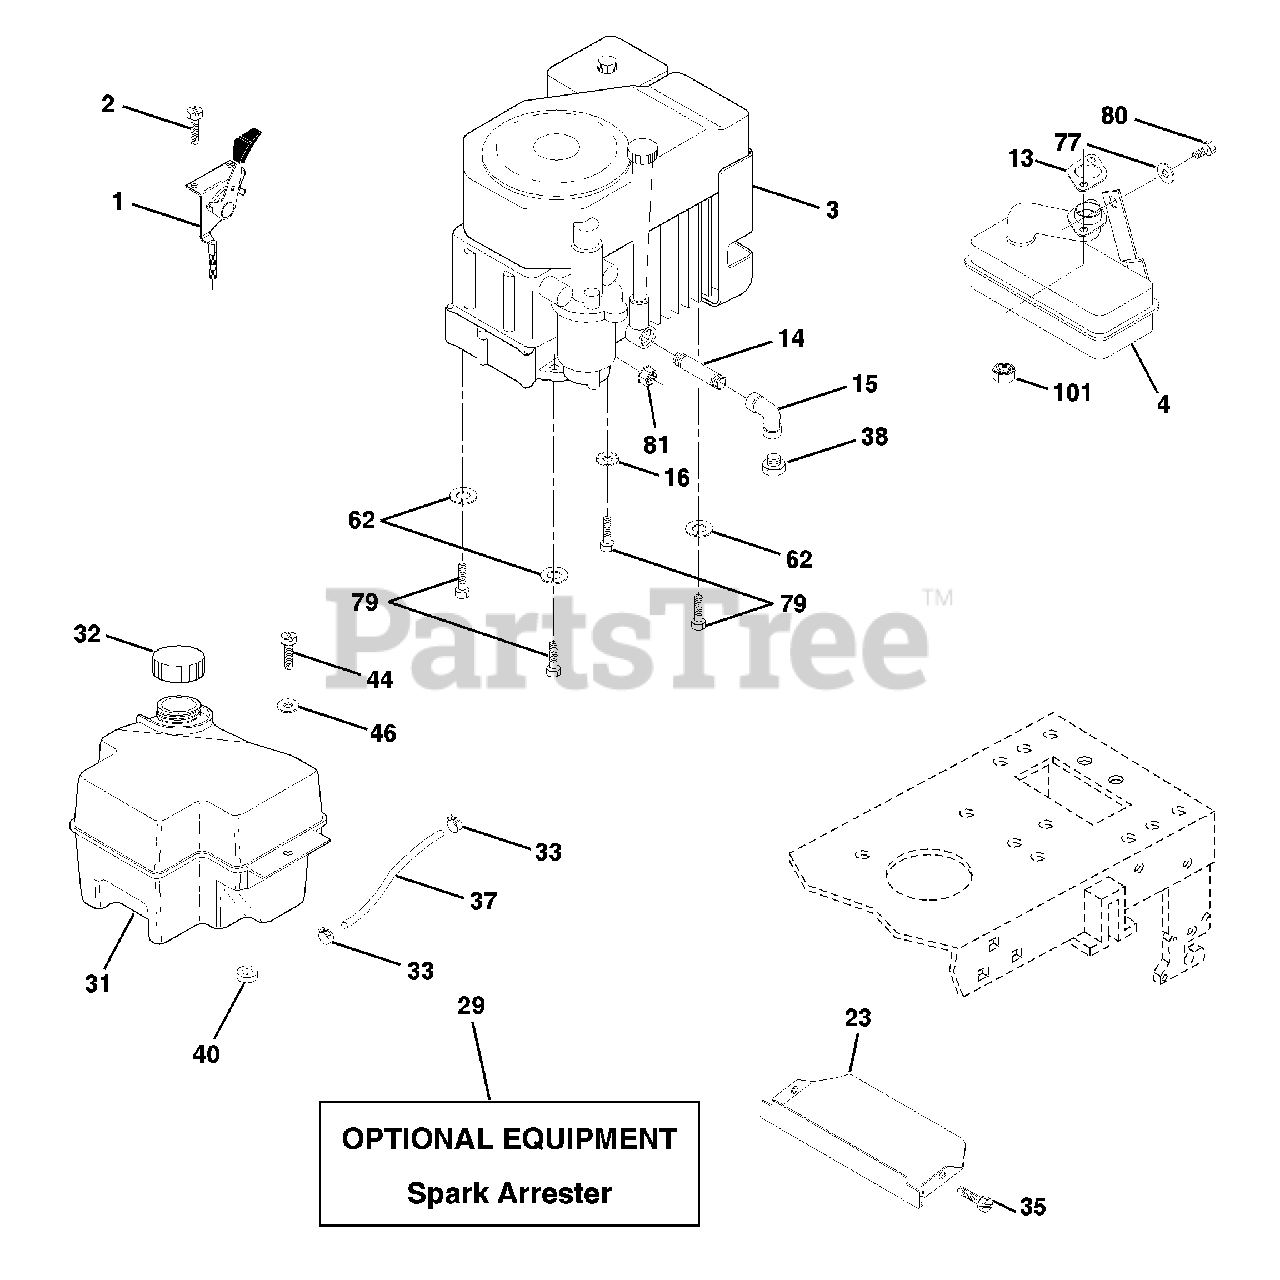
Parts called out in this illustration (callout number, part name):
1	Control THT/CH 27 LH FLAG DOM
2	Screw Hex Thd Cut 1/4-20 x 5/8 T
4	Muffler LT Kohler
13	Gasket Kohler CV13-CV16.5
14	Nipple Pipe 3/8 Npt X 3-1/2
15	Elbow Std 90 Degree 3/8-18 Npt
16	Washer Lock Ext Tooth 5/16
23	Shield Brn/Dbr Guard
29	Kit Spark Arrestor (Flat Scrn)
31	Tank Fuel Front 2 00
32	Cap Asm Fuel W/sym Vented
33	Clamp Hose Black
35	Screw
37	Line Fuel 20"
38	Plug Oil Drain
40	Bushing Snap Nyl Blk Fuel Line
44	Screw Hexwsh Thdrol 1/4-20x3/4
46	Washer 9/32 X 7/8 X 16 Ga
62	Washer Lock Hvy Hlcl Spr 5/16
77	Washer 5/16 x 3/4 x 16 Ga.
79	Bolt Hex
80	Bolt Hex Hd 5/16-18 UNC x 1/2
81	Nut Flange 1/4-20 Starter Nut
101	Nut Flange M8-1.25 Non-Lk Zinc
